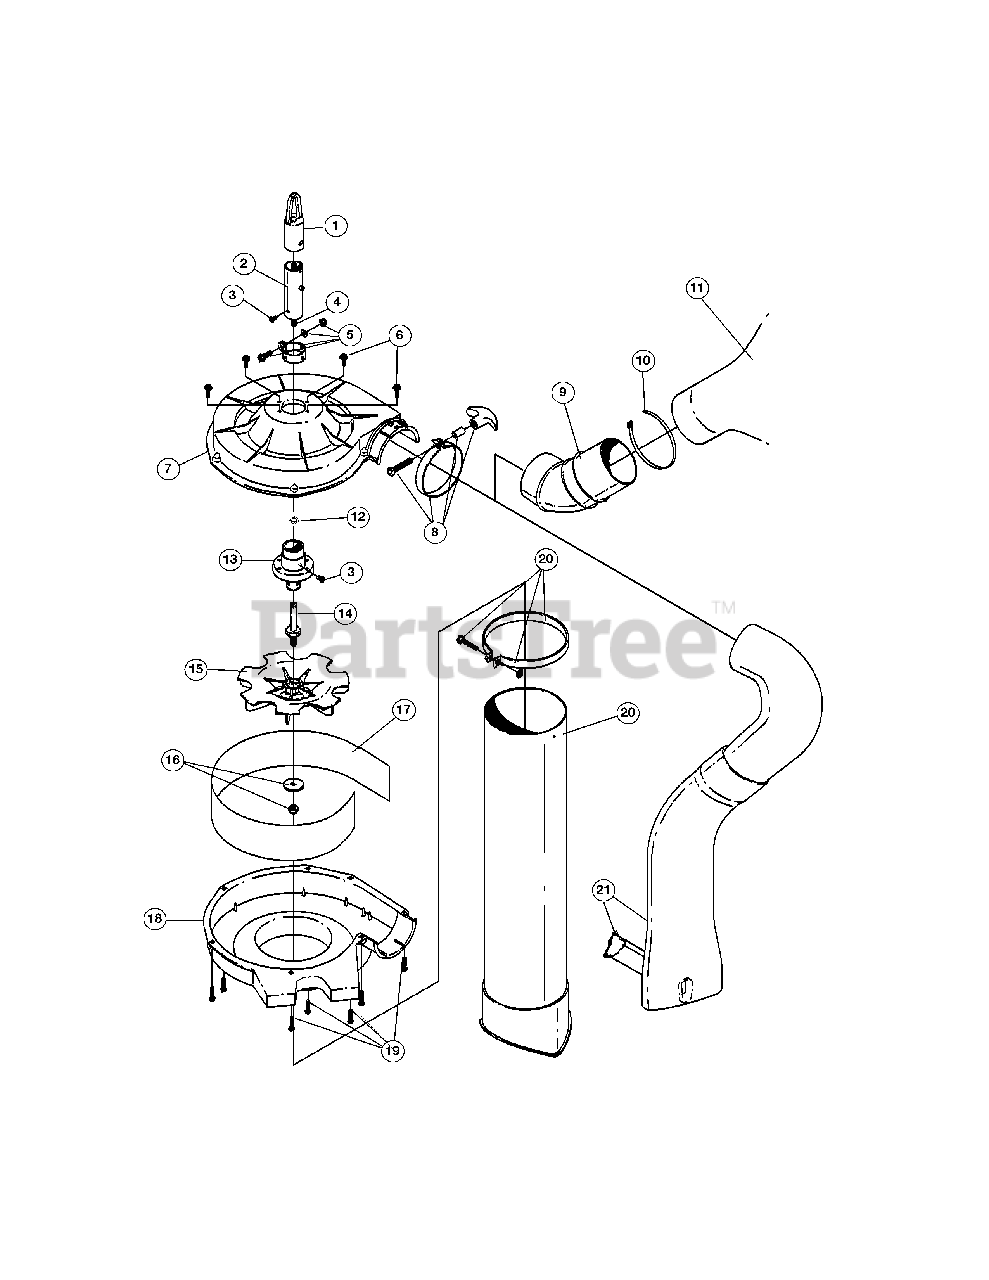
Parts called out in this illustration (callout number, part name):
1	Hanger
2	Boom Assembly
3	Anti-Rotation Screw
4	Drive Shaft Assembly
5	Lower Clamp Assembly (includes 3)
6	Mounting Screw
7	Upper Housing
8	Clamp Assembly
11	Vacuum Bag Assembly (includes items 9 & 10)
12	Palnut
13	Bushing Housing Assembly
14	Impeller Shaft
15	Impeller
16	Nut and Washer Assembly
18	Lower Housing
19	Mounting Screw
20	Vacuum Tube Assembly
21	Blower Tube Assembly
